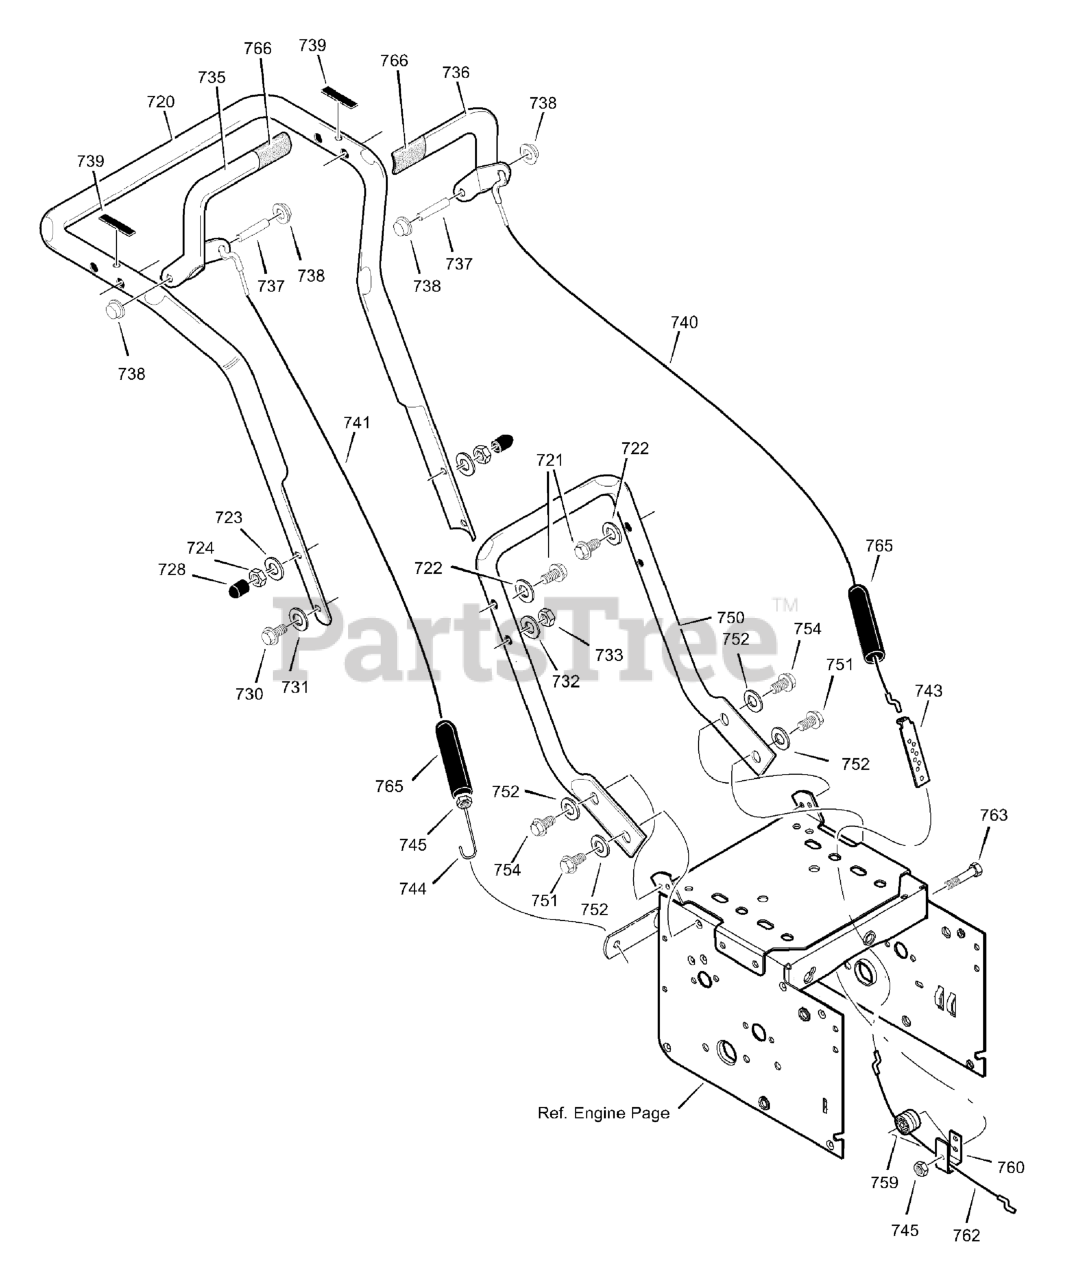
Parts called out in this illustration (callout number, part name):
720	HANDLE, UPPER
721	SCREW, 3/8-16 x 3.00
722	WASHER, FLAT
723	WASHER
724	NUT, 3/8-16
728	STOP, PLASTIC
730	SCREW, 3/8-16 X 2
731	WASHER, FLAT
732	WASHER
733	NUT, 3/8-16
735	HANDLE, RIGHT
736	HANDLE, LEFT
737	PIN, PIVOT CLUTCH
738	NUT, PUSH ON CAP
739	BUMPER, RECTANGLE
740	CABLE, DRIVE
741	CABLE, AUGER CLUTCH
743	BRACKET, CABLE ADJUSTER
744	SPRING, AUGER CLUTCH
745	NUT, 1/4-20
750	HANDLE, LOWER
751	SCREW, TAP 5/16-18 X .75
752	WASHER, SPTLK
754	SCREW, TAP 5/16-18 X .75
759	SPOOL-CABLE, AUGRT CLUTCH
760	BRACKET, CABLE SPOOL YZ
762	CABLE, LOWER DRIVE 12"
763	BOLT, HEX 1/4-20 X 1.5
765	BOOT, CLUTCH SPRING
